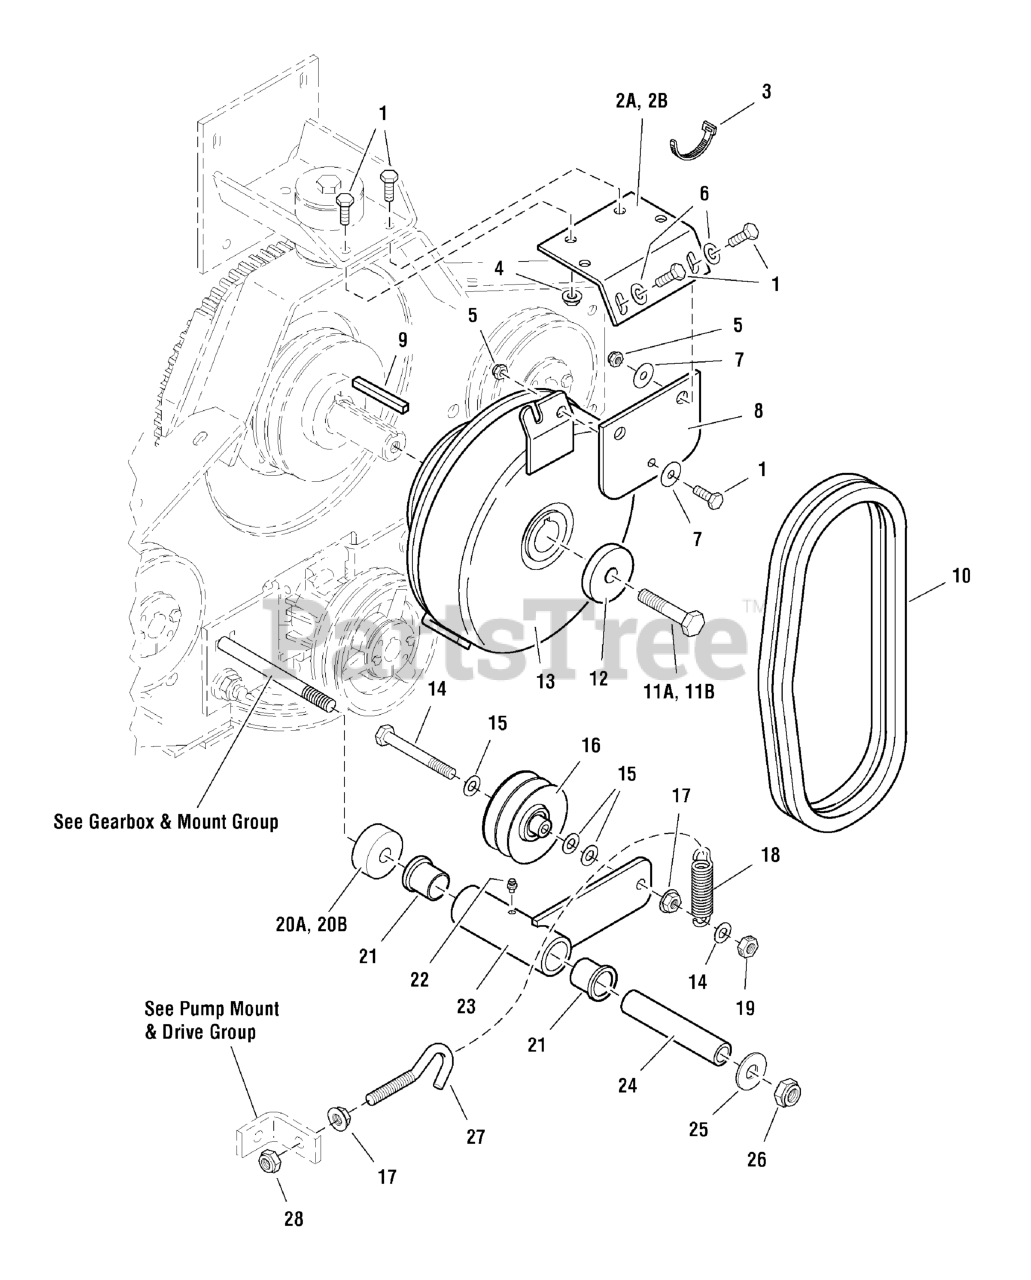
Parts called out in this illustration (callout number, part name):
1	BOLT, 5/16-18 X 1 GD5 YZ
2A	CLUTCH ANCHOR
2B	CLUTCH ANCHOR
3	TIE WRAP, 5-1/2"
4	NUT, 5/16-18 HEX SERRATED FLANGE (SMALL)
5	NUT, 5/16-24 HEX NYLON LOCK
6	WASHER, 5/16" SAE
7	WASHER, Clutch Anchor
8	CLUTCH ANCHOR PAD
9	KEY, 1/4 SQ. X 3
10	BELT, Clutch Drive (set of 2)
11A	CRANKSHAFT BOLT, 7/16 x 1-1/2
11B	CRANKSHAFT BOLT, 7/16 x 3-3/4
12	SPACER, .45 x 1.88 x .38
14	BOLT, 3/8-16 X 3" GD5 CZ
15	WASHER, 3/8 SAE
16	PULLEY, Idler
17	NUT, 3/8-16 Hex Serrated Flange
18	SPRING, Extension
19	NUT, 3/8-16 Hex Side Lock
20A	SPACER, .51 x 1.75 x .75
20B	SPACER, .51 x 1.75 x .50
21	BUSHING, Flange
22	GREASE FITTING
23	CLUTCH DRIVE IDLER ARM
24	PIVOT SLEEVE, Long
25	WASHER, 1/2 SAE
26	NUT, 1/2-13 HEX NYLON LOCK
27	SCREW HOOK, 3/8-16 x 4-1/4
28	NUT, 3/8-16 HEX NYLON LOCK
